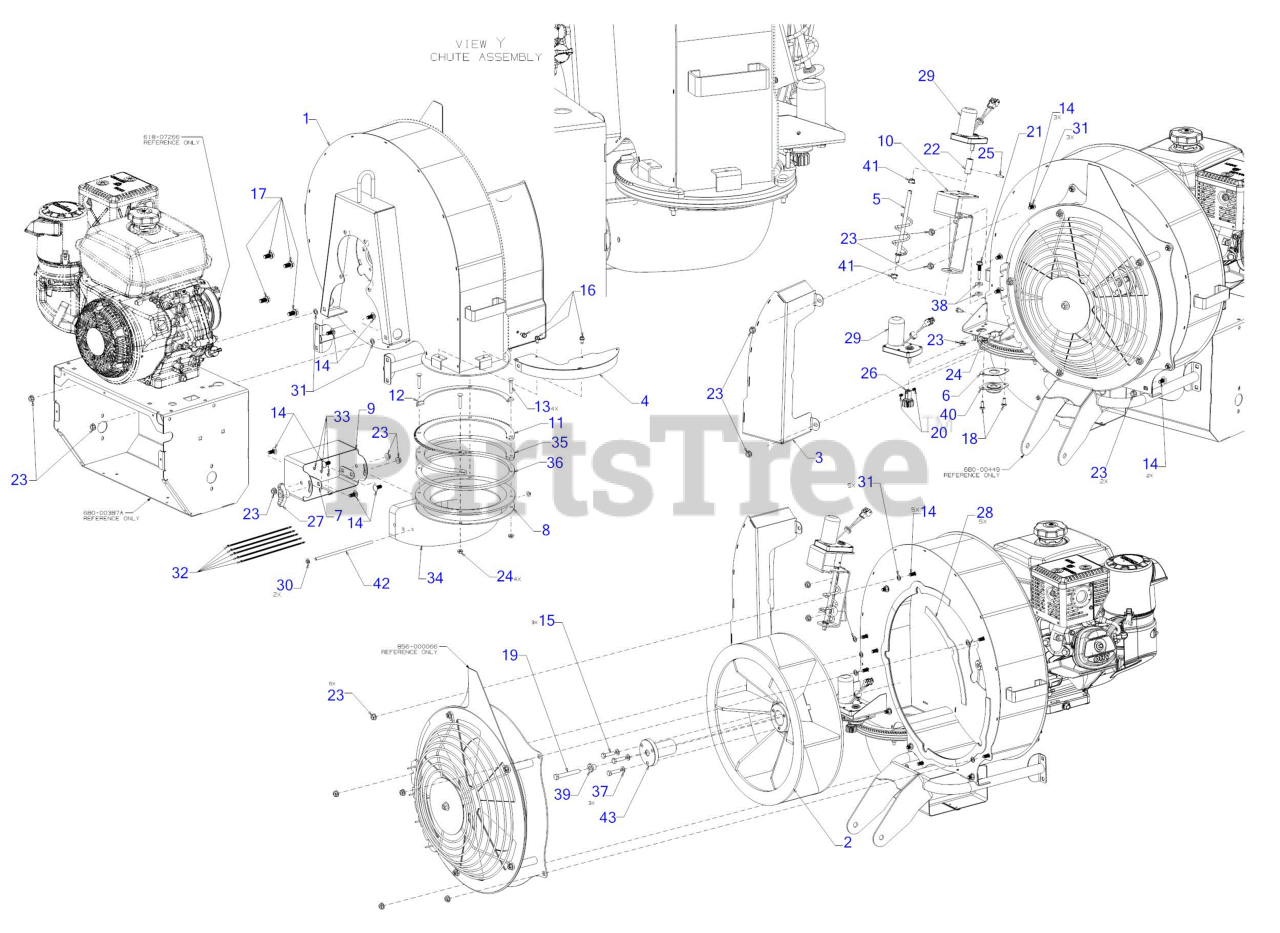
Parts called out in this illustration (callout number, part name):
1	IMPELLER/BLOWER HOUSING ASSEMBLY
2	IMPELLER ASSEMBLY
5	CHUTE CRANK ASSEMBLY
8	CHUTE RING GUIDE
11	NOZZLE RING GEAR
12	CHUTE GEAR STOP PLATE
13	CARRIAGE BOLT 1/4-20 x 1.50
14	CARRIAGE BOLT 5/16-18 x .75
15	SCREW 5/16-18 x 1.25 GR5
16	SCREW 1/4-20 X.500
17	BOLT - 3/8-16:.75:GR5:PATCH LOCK
18	SCREW 1/4-20 x .620 GR5
19	SCREW 3/8-24 x 2.75 GR5
20	SCREW 1/4-20 x .38
21	BELT KEEPER ROD .25 x 1.585
22	ADAPTER SHAFT
23	FLANGE NUT
24	LOCK NUT 1/4
26	MOTOR GEAR
27	WING KNOB 5/16-18
28	BLOWER HOUSING SEAL
29	CHUTE ROTATION MOTOR (NO PITCH)
30	PUSH NUT
32	TIE CABLE 8.5 LG
34	BLOWER DISCHARGE CHUTE
35	CHUTE TOP GUIDE RING
36	CHUTE RING GUIDE
37	FLAT WASHER
38	FLAT WASHER
39	SHOULDER SPACER .875 X .38 X .55
40	BALL BEARING
41	BUSHING .380 ID
43	BLOWER IMPELLER LOCK FLANGE
